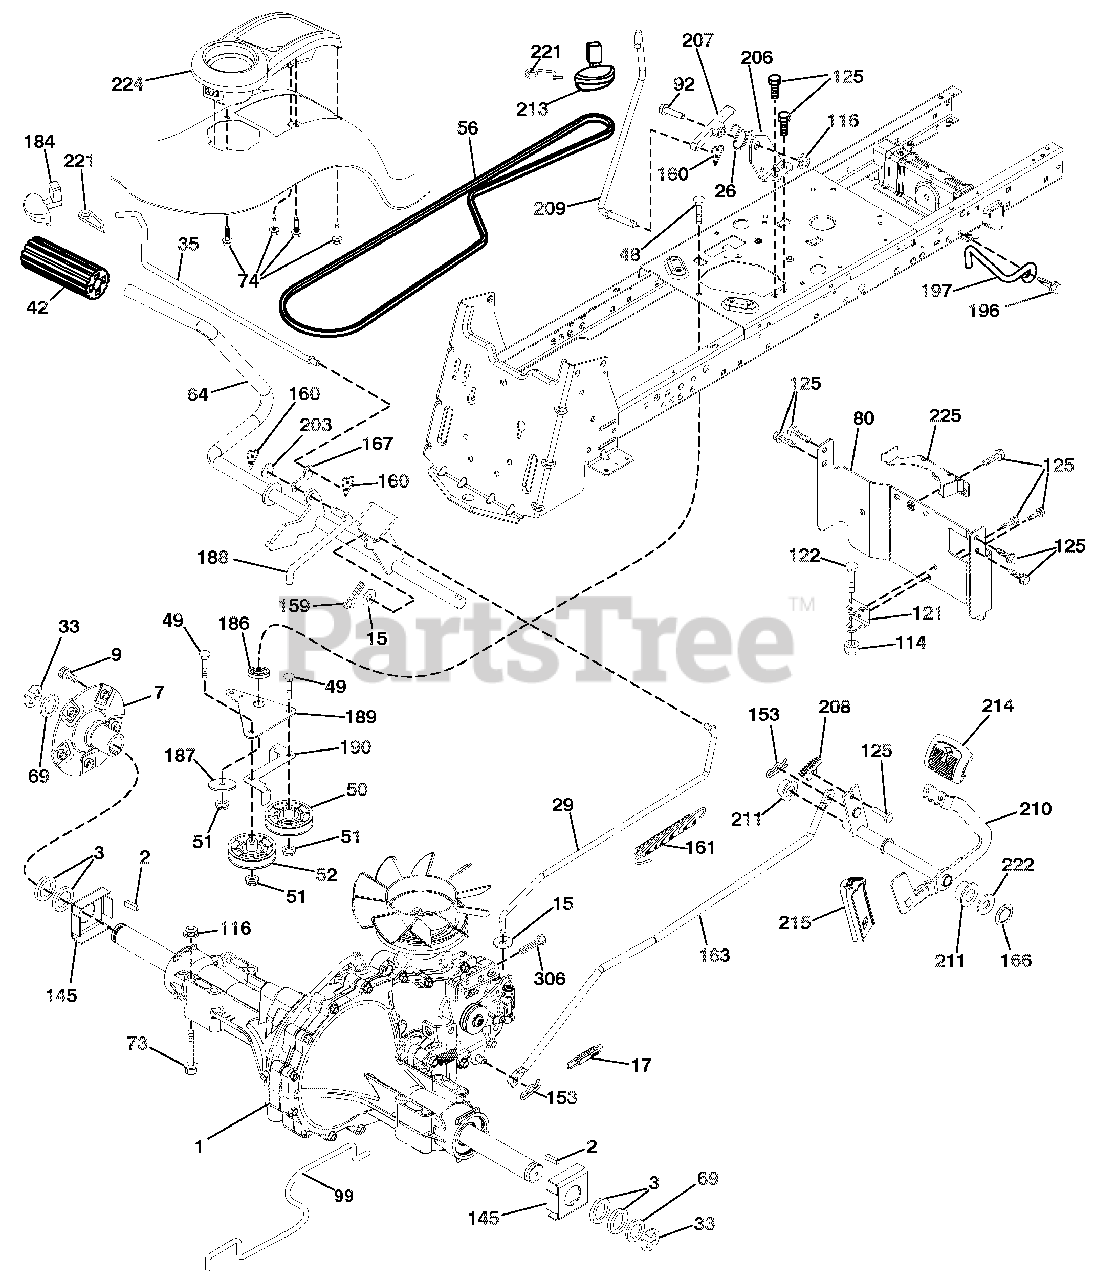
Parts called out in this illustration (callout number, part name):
1	TRANSAXLE, HYDRO G7-BCBB-1XDC-IECX (418183) (ORDER PARTS FROM TRANSAXLE MANUFACTURER.)
2	KEY 1/4 X 2.5
3	WASHER THRUST AXLE HARDENED
7	HUB ASM. WHEEL
9	BOLT HUB WHEEL
15	WASHER.13/32 X 13/16 X 16 GA.
17	SPRING.BRAKE.GT.TEX
26	SPRING.RETURN.CRUISE
29	ROD.BRAKE
35	ROD.BRAKE.PARKING.LT.TEX
42	COVER PEDAL BLK ROUND
48	BOLT.CARR.SH.3/8-16X1-1/2.GR5
49	BOLT.RDHD.3/8-16UNCX1-3/4.GR5
50	IDLER.FLAT.910"OFFSET
51	Nut, Hex, Flangelock 3/8-16
52	IDLER.V-GROOVE.910"OFFSET
56	GROUND DRIVE BELT
64	SHAFT ASM.PEDAL.BRK.CNTRL.PCH
69	WASHER 1-1/32 X 1-5/8 X 16 GA.
73	BOLT.HEX. 5/16-18 X 3 GR. 5
74	SCREW.HEX.WSH.HI-LO.1/4X1/2UNC
80	STRAP.TORQUE
92	Bolt, Hex Head 5/16-18 x 1-1/4
99	SPRING.BYPASS
114	Locknut, Washer Insert 5/16-18
116	Nut, Lock Hex Flange 5/16-18 u
121	BRACKET.STRAP.TORQUE.T/A.3500
122	BOLT.5/16-18 x 2.50
125	SCREW.5/16-18X3/4.SMGML.TAP/BL
145	WASHER.AXLE.FLANGE
153	RETAINER SPRING
159	PIN.COTTER.1/8 X 3/4.CAD.
160	RETAINER.CLIP(M).DIA.290
161	SPRING.RETURN.CLUTCH.6.75
163	ROD.PEDAL.CONTROL
166	NUT PUSH .625
167	LATCH.BRAKE.PARKING
184	HANDLE.PARKNG.BRAKE.LT.TEX.667
186	SPACER.RETAINER
187	WASHER.13/32 X 2 X 10 GA.
188	LINK.CLUTCH.GROUND DRIVE
189	BELLCRANK.GROUND.DRIVE
190	KEEPER.BELLCRANK.GROUND.DRIVE
196	SCREW.3/8-16X1.SMGML.TAP/R.BLK
197	LINK CLUTCH ANTI-ROTATION
203	Washer 11/32 x 11/16 x 16 Ga.
206	BRACKET MOUNT LATCH CRUISE
207	LATCH.CONTROL.CRUISE
208	GEAR SECTOR.CONTROL.CRUISE
209	ROD.CONTROL.CRUISE
210	ROCKER ASM. PEDAL CONTROL
211	BEARING.NYLON.BLK..629 ID.
213	KNOB.CONTROL.CRUISE
214	PAD PEDAL FORWARD
215	PEDAL.REVERSE
221	RETAINER.SPRING.CLIP.HANDLE
222	WASHER.21/32X1-1/4.10GA.N/PLTD
224	CONSOLE.TOOLBOX
225	KEEPER.BELT T/A
306	Pin Cotter 1/8 x 1 Cad
